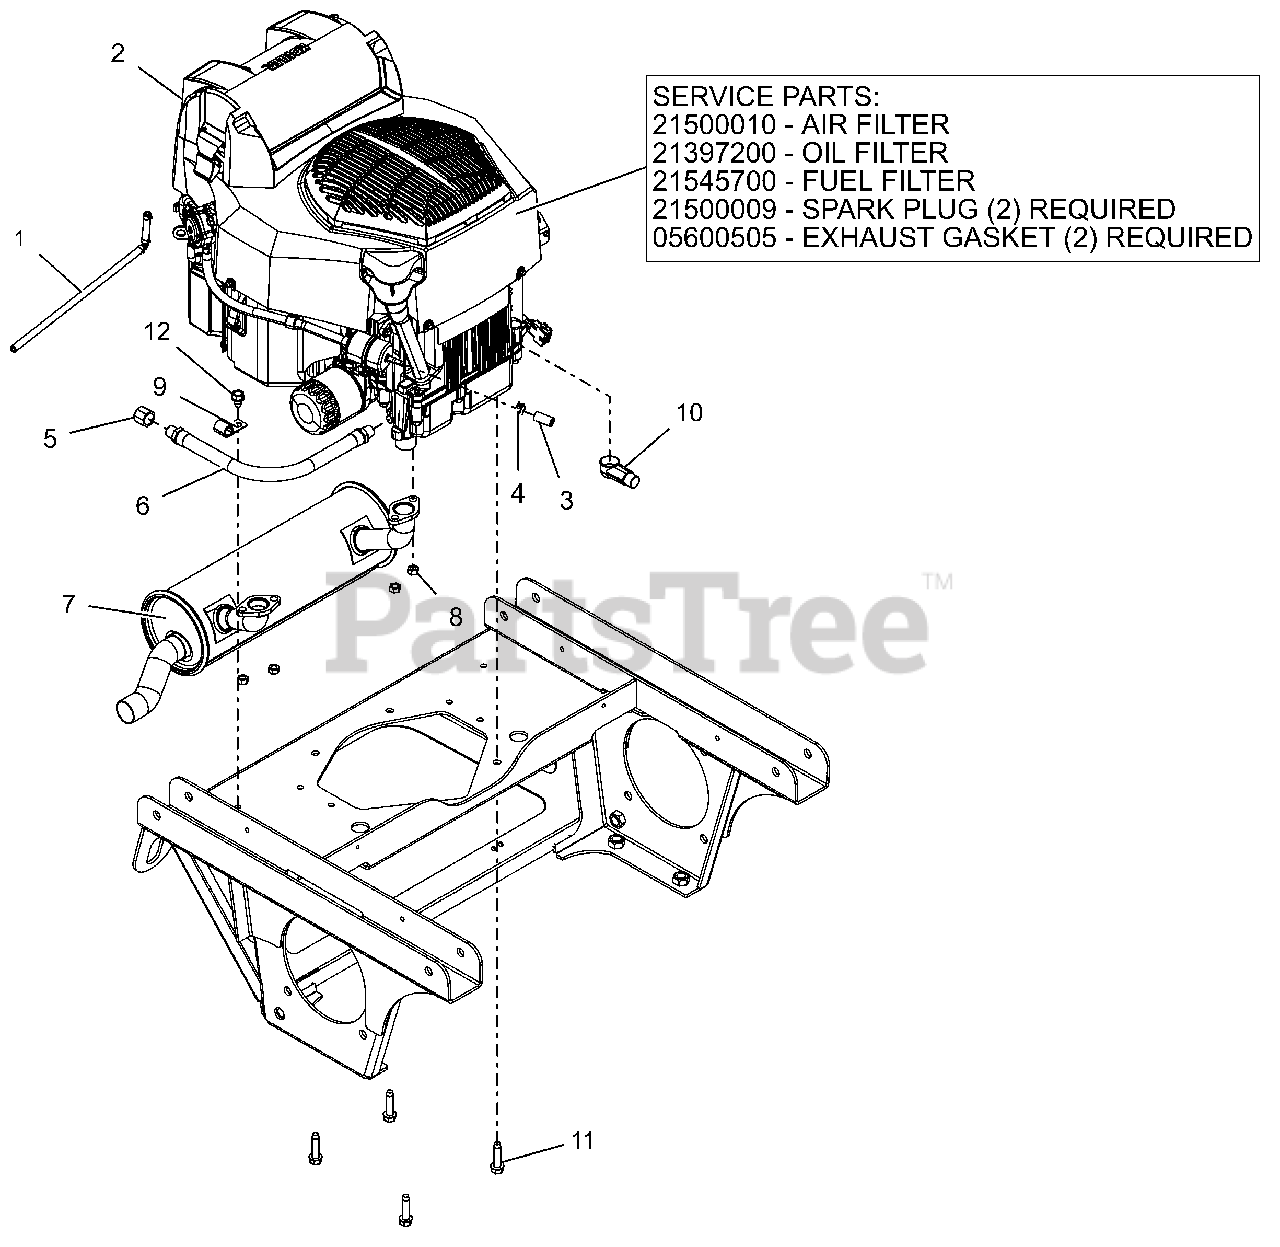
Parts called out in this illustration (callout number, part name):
1	ASM, VAPOR LINE
2	ENGINE, KOHLER ZT740 CONFIDANT
2	AIR CLEANER, KOHLER CONFIDANT
2	FILTER, OIL - KOH CV20
2	FILTER-FUEL KOHLER COURAGE PRO
2	PLUG, SPARK KOHLER
2	GASKET, MUFFLER KOHLER TWIN
3	HOSE, .25 LOW-PERM BULK GAS
4	CLAMP, FUEL LINE
5	PIPE CAP 3/8 NPT FEMALE
6	HOSE,HYD .38-14-0K M6N0-M6N0
7	MUFFLER, ZT730/ZT740
8	NUT-LK-TOP M8-1.25 YWZC
10	BOOT, .65ID POS
11	@SCR-TAP .38-16X1.50 HWH TR YZ
12	@SCR-TAP .38-16X.50 HWH TR YWZ
